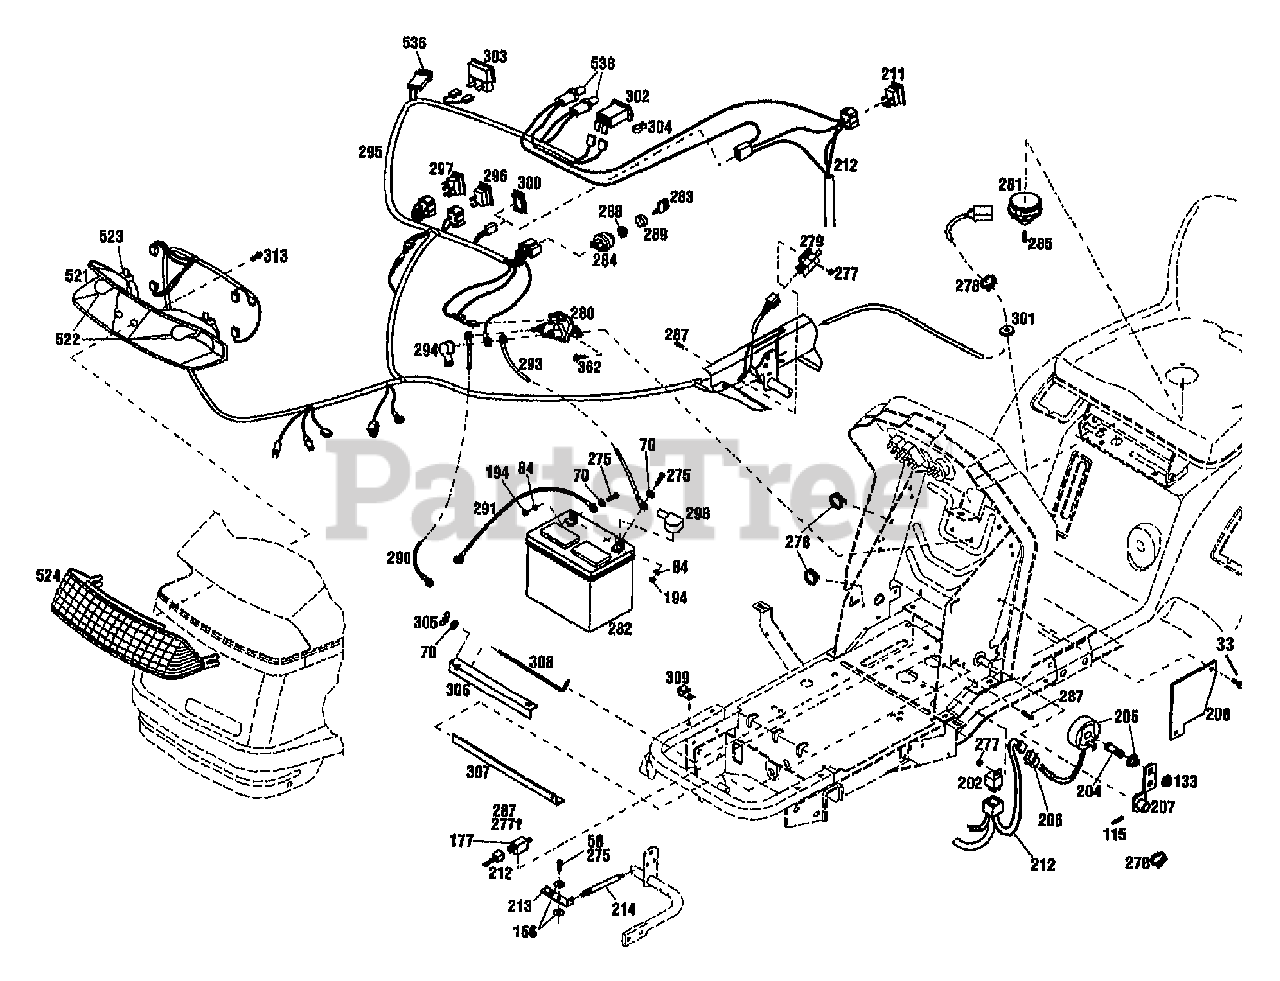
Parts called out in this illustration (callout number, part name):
33	SCR-HFLK 5/16-18X.75 {13040}
58	NUT-HT LK 1/4-20 {13040}
70	WASHER-FLAT 1/4 SAE
84	WASHER-LK .25 ZP
115	PIN-ROLL .188X1.0 {13040}
133	NUT-WHIZ LOCK {13040}
166	WASHER-FLAT 1.25X.28X.062 ZP {13040}
177	SWITCH
194	NUT-HEX 1/4-20 ZP
202	RELAY-SPEED CONTROL {13040}
204	SCR-SPECIAL {13040}
206	PIN-TERM HOUSING {13040}
207	ARM-CRUISE {13040}
208	PLATE-CRUISE {13040}
211	SWITCH-CRUISE {13040}
212	HARNESS-CRUISE {13040}
213	ARM-CRUISE {13040}
214	SPRING {13040}
275	SCR-HH 1/4-20X.625 G5 ZP {13040}
277	NUT W/LKWASHER 10-24 ZP
278	TIE-CABLE NYLON BLACK
279	SWITCH {13040}
280	SOLENOID
281	SWITCH-SEAT
282	BATTERY
283	KEY-IGNITION
284	SWITCH-IGNITION
285	SCR-PHP 1/4-20X.50 ZP
287	SCR-HHS 10-24X.625 ZP
288	NUT-SWITCH
289	CAP-SWITCH
290	ASSM-BLADE COUPLING
291	CABLE-BATTERY (-)
293	CABLE-BATTERY
294	BOOT-SOLENOID
295	HARNESS-MAIN ELECTRICAL
296	SWITCH-LIGHT
297	SWITCH-PTO
298	BOOT-TERMINAL
300	COVER-SWITCH {13039}
301	GROMMET
302	METER-HOUR {13040}
303	AMMETER {13040}
304	CLIP-TINNERMAN {13040}
305	NUT-WING
306	CLAMP-BATTERY
307	BRKT-BATTERY LOWER
308	SCR-HOOK
309	CLIP-J
362	SCR 1/4-20X.5 FL SELF TAP
521	HEADLGT-REFL (PART OF 1772002)
522	LIGHTBULB
523	SOCKET
524	LENSE-HEADLIGHT
536	BRKT-MTG HGT ADJ
538	LIGHTBULB
